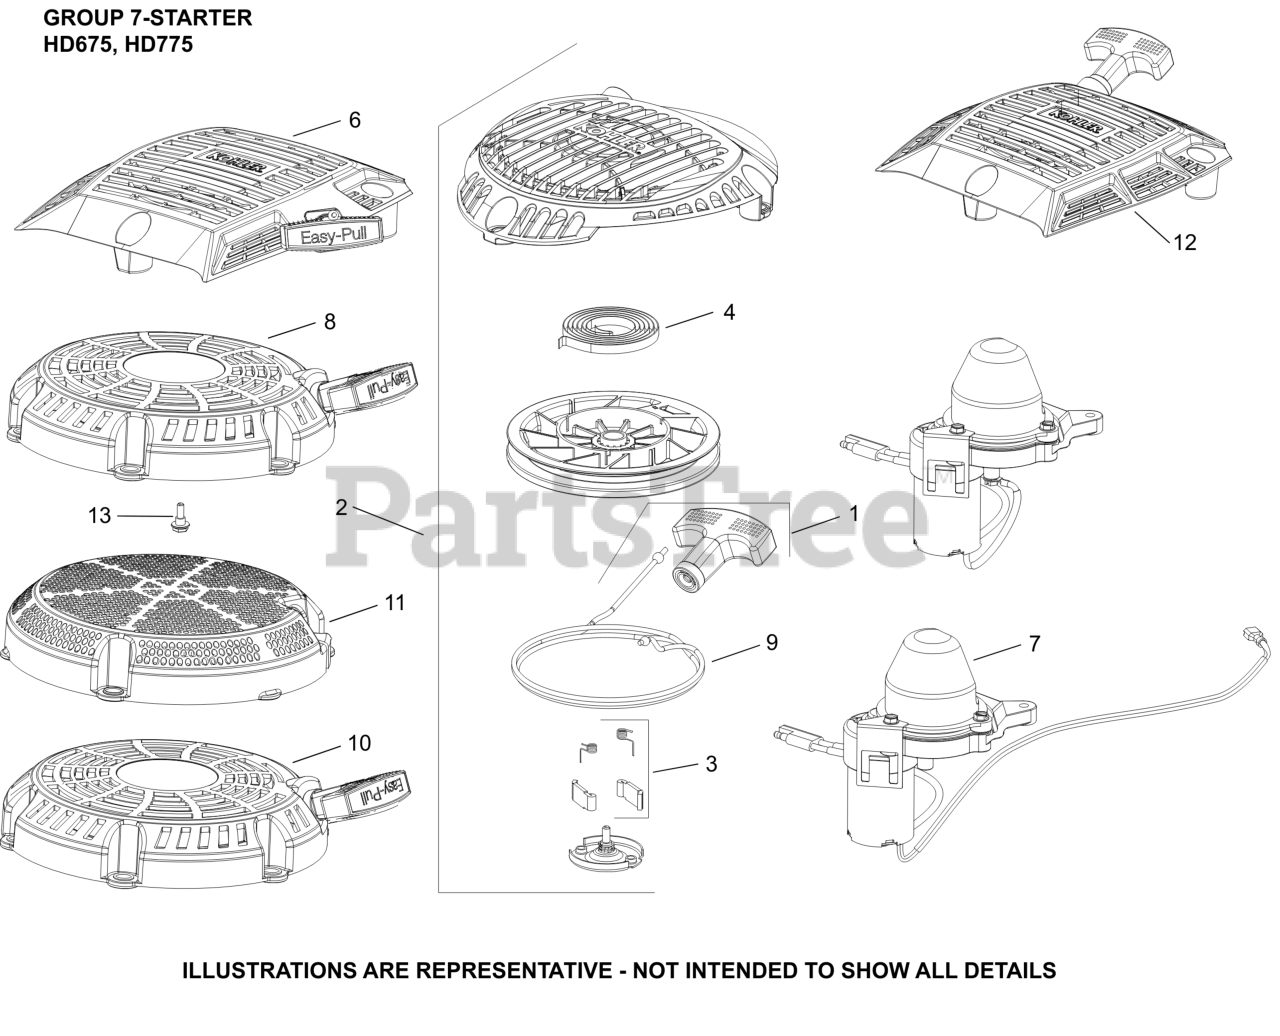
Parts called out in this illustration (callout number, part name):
1	KIT, STARTER ROPE W/HANDLE
3	KIT, PAWL REPAIR
8	STARTER ASSEMBLY, RETRACTABLE
9	KIT, STARTER ROPE W/HANDLE
